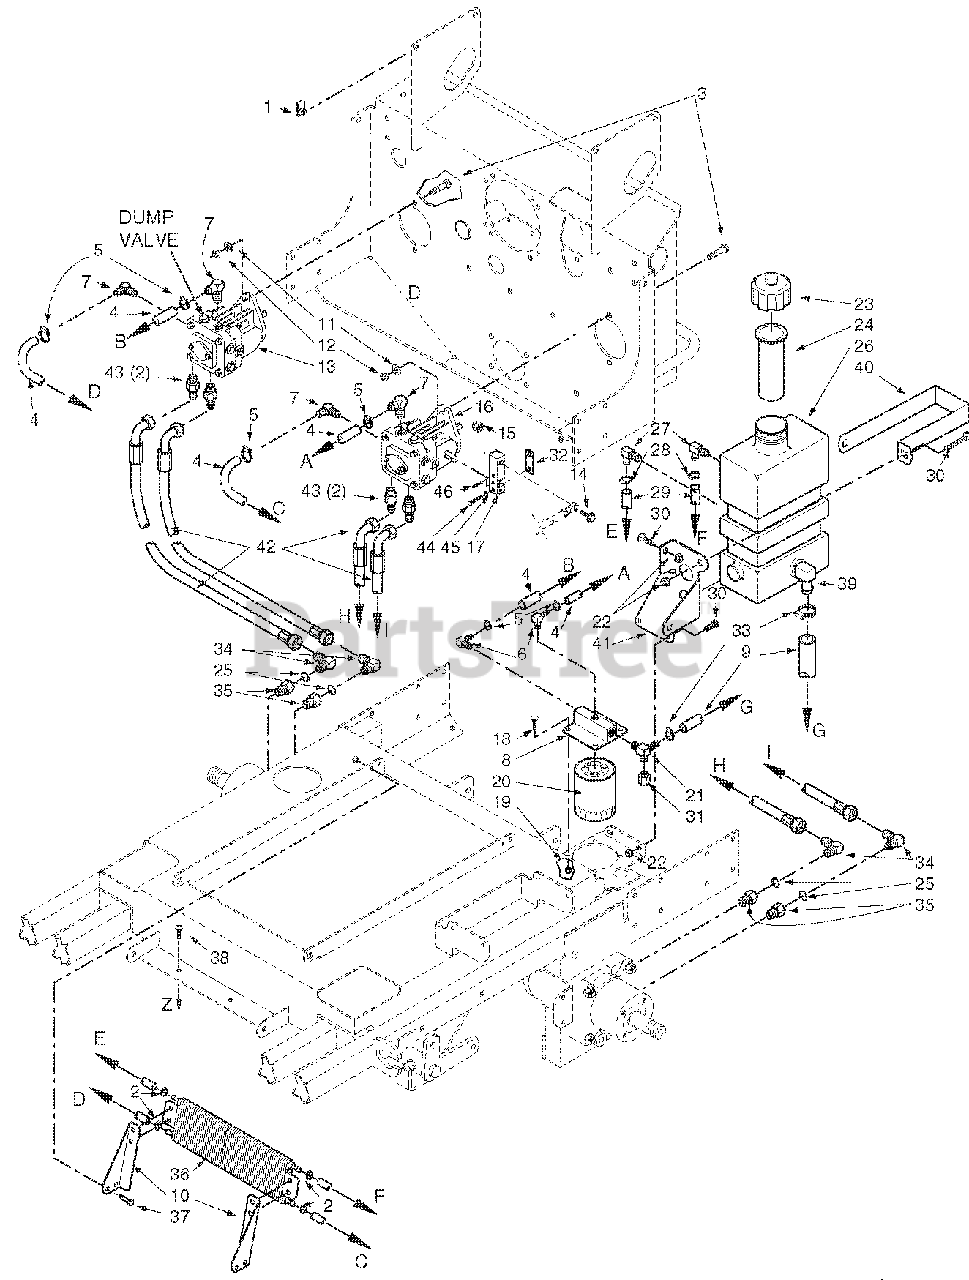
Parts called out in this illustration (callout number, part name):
1	U-Nut 1/4-20
2	Hose Clamp, 0.69" Dia.
3	Bolt, Hex Head 1/4-20 x 2.0"
4	Hose, 3/8" ID Pushlock
5	Clamp, Hose 1/2"
6	Elbow, 90 Degree - 1/4" NPT x 3/8" Hose
7	Elbow, 90 Degree - 9/16" O-Ring x 3/8" Hose
8	Oil Filter Base
9	Hose Assembly, 1/2" ID
10	Mounting Bracket - LH, Oil Cooler
11	Flatwasher, 3/8" (.391 x .938 x .105") Grade 8
12	Nut, Hex Elastic Stop 3/8-16
13	Pump w/Fan, Right Hand
14	Bolt, Hex Head, 3/8-16 x 1-1/4"
15	Nut, Hex, Elastic Stop 3/8-16
16	Pump w/Fan, Left Hand
17	Block, Pump Control
18	Bolt, Hex Head 5/16-18 x 1.0" Zinc
19	Nut, Serrated Flange 5/16-18
20	Oil Filter
21	Tee, 3/4" O-Ring x JIC x 1/2" Hose
22	Nut, Hex Elastic Stop 1/4-20
23	Cap, Hydraulic Tank
24	Insert, Filler Neck
25	O-Ring
26	Oil Reservoir Assembly
27	Elbow, 90 Degree .38" Hose
28	Hose Clamp, 0.69" Dia.
29	Hose, 3/8" ID, Pushlock
30	Screw, Phillips Head, 1/4-20
32	Clamp Plate, Pump Control
33	Clamp, Hose
34	Elbow, 90 Degree, 1/2" x 1/2"
35	Bushing, 7/8"-14 JIC x 3/4"-16 O-Ring
36	Cooler, Oil
37	Bolt, Hex Head 5/16-18 x 3/4"
38	Bolt, Carraige 1/4-20 x 3/4"
39	Elbow, 90 Degree
40	Strap, Hydraulic Tank
41	Support Bracket, Hydraulic Tank
42	Hose Assembly, Pump
43	Union, 3/4"-16 JIC x 3/4"-16 O-Ring
44	Bolt, Hex Head, 1/4-20 x 1-1/4"
45	Lockwasher, 1/4" Spring
46	Roll Pin, Spring 3/16 x 3/4"
